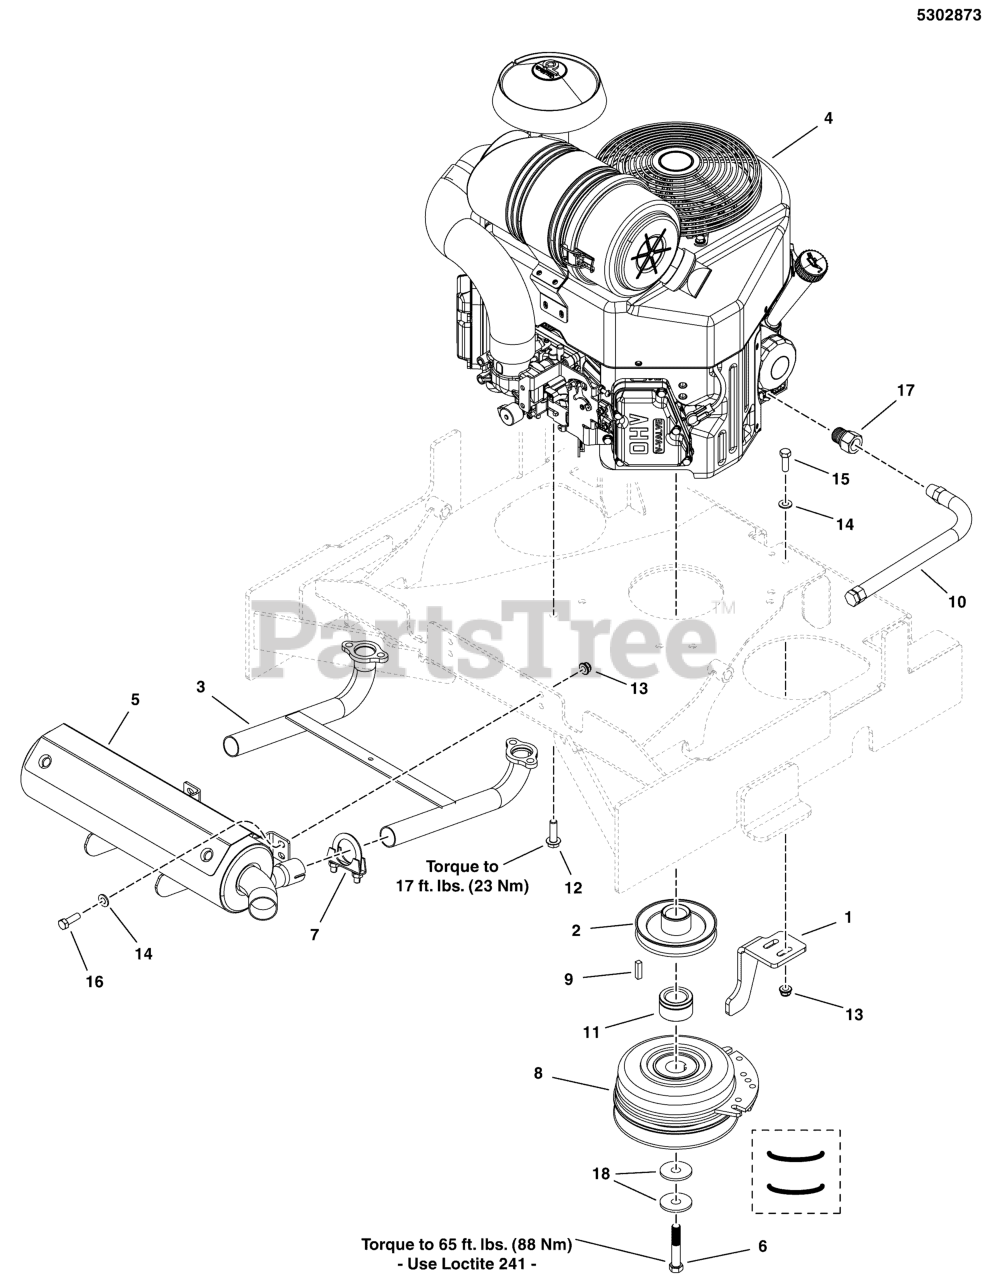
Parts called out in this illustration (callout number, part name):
1	PLATE, CLUTCH ANCHOR - RED
2	PULLEY, CRANKSHAFT, 4.5DX1.125IDX1.97LG
3	MANIFOLD, KAWA, HOR, SW30
5	MUFFLER, KAWA, HORIZONTAL
6	BOLT, CRANKSHAFT, 7/16-20 X 3, GD8
7	CLAMP, EXHAUST EXTENSION
8	* CLUTCH, 5218-134, WARNER
9	KEY, 1/4 SQ X 1
10	HOSE, OIL DRAIN
11	SPACER, 1.13 X 1.75 X 1.03, CZ
12	BOLT,HEX FLG,SER GD5 3/8-16X1-1/4PACH CZ
13	NUT, 5/16-18 HEX NYLOCK FLANGE
14	WASHER, 5/16" SAE
15	BOLT, 5/16-18 X 1-1/4 GD5 YZ
16	BOLT, 5/16-18 X 3/4 GD5
17	ADAPTER-OIL DRAIN
18	BELLEVILLE WASHER 1.1875 X .442 X .089
